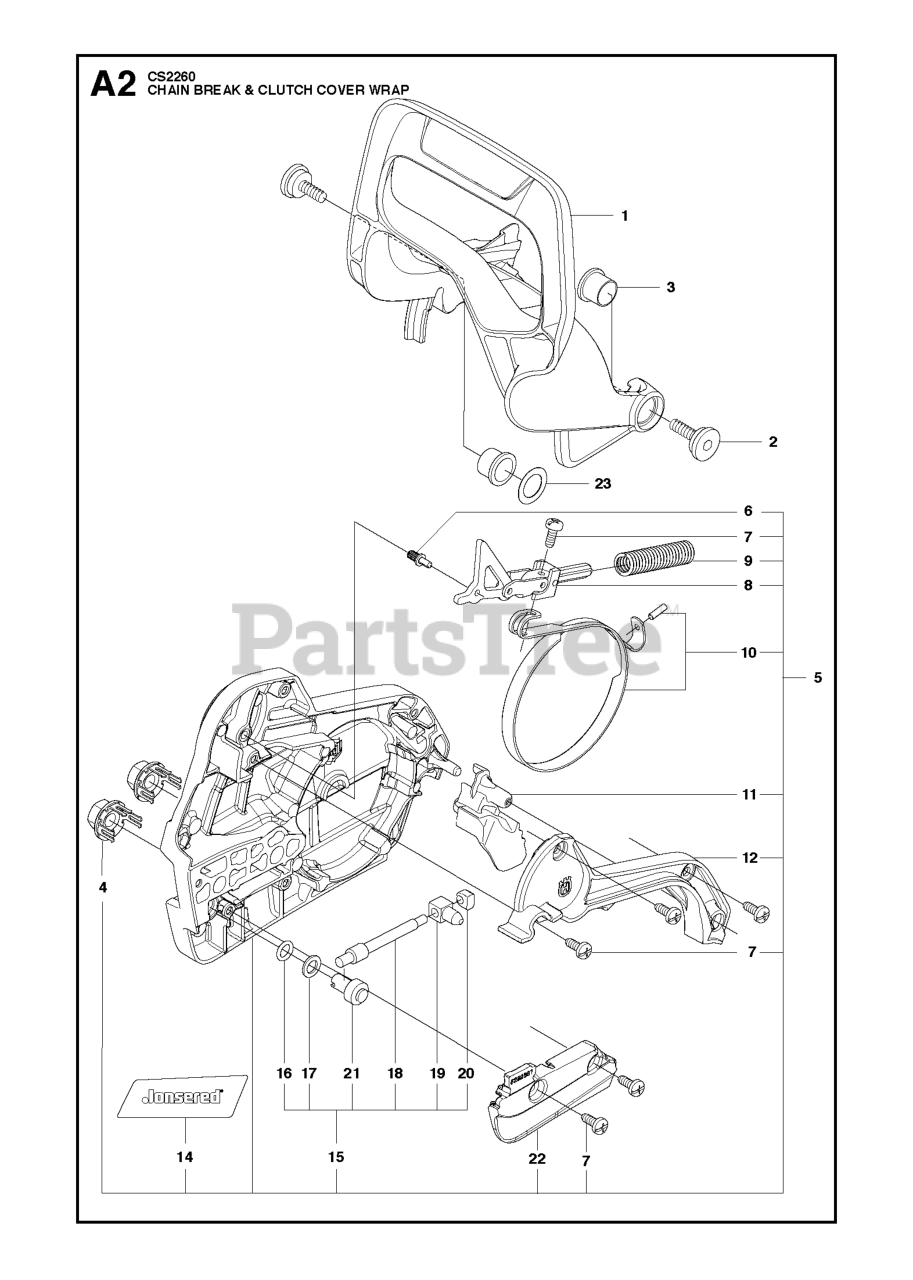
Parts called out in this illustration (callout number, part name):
1	HAND GUARD
4	NUT RETAINER ASSY
6	PIN
7	SCREW
8	KNEE JOINT ASSY
9	SPRING
10	BRAKE BAND ASSY
11	GUARD
12	COVER BRAKE COVER JONSERED BLA
14	DECAL JONSERED 60CC CLUTCH COV
15	CHAIN TENSIONER KIT
16	O-RING
17	WASHER
18	SCREW
19	PAWL
20	SLEEVE
21	WORM WHEEL
22	CHAIN GUIDE WRAP AROUND JONSER
23	WASHER STEEL
